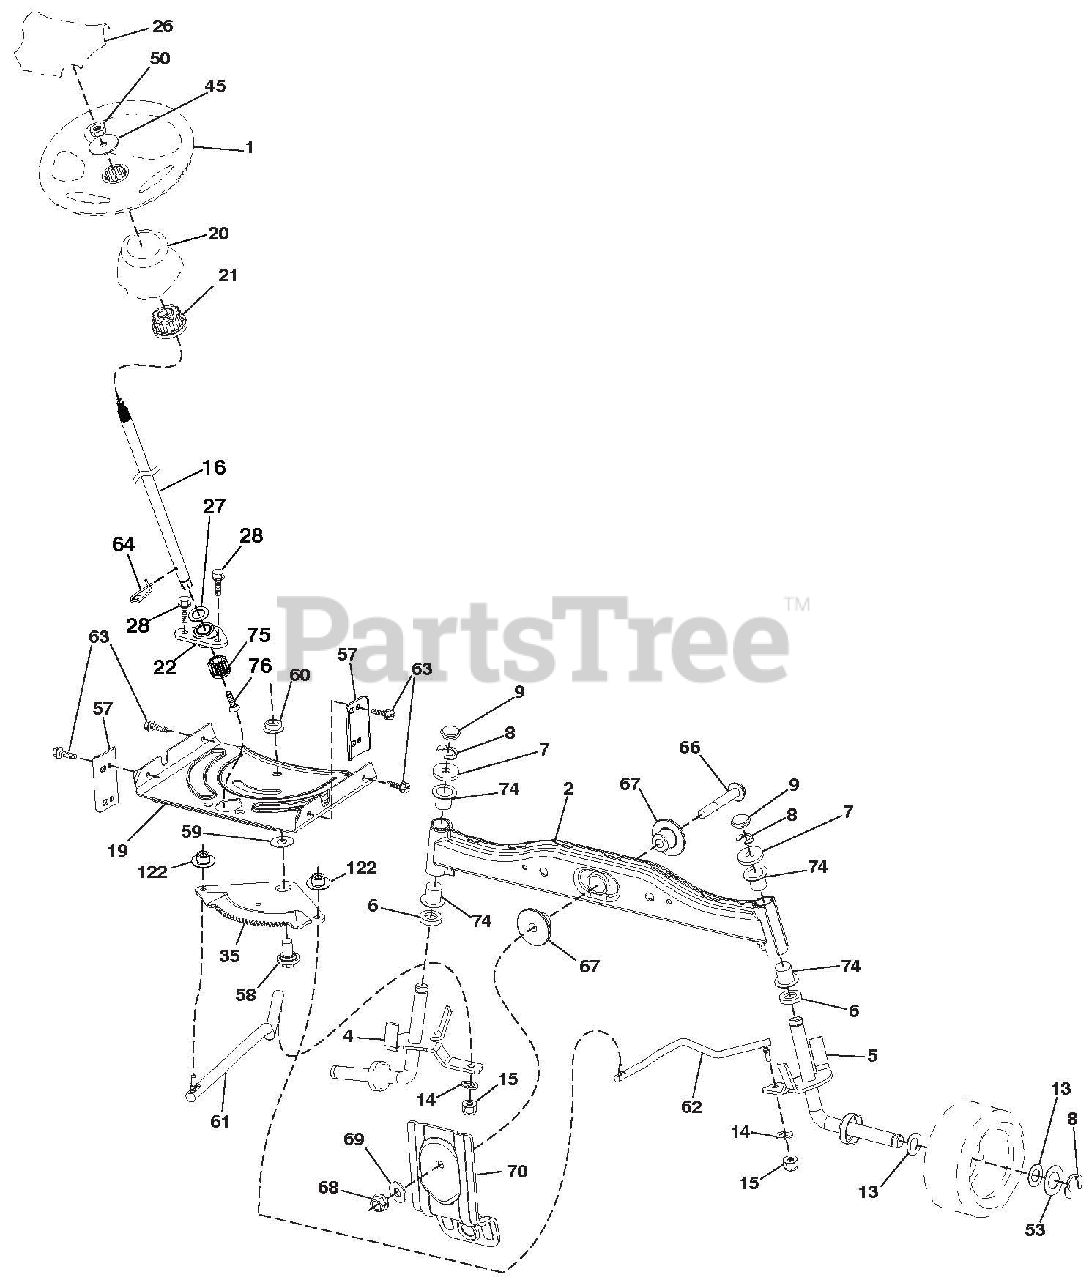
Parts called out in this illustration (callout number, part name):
1	WHEEL STEERING
2	AXLE ASM.WELDED
4	SPINDLE.WELDED.LH.15"TEX
5	SPINDLE.WELDED.RH.15"TEX
6	WAHSER THRUST .75 X 1.230
7	WASHER.25/32 X 1-5/8 X 16GA.
8	RING.KLIP.#T5304-75
9	CAP.SPINDLE.FR.TOP.BLK.
13	WASHER.25/32 X 1 1/4 X 16 GA.
14	Washer, Lock 3/8
15	NUT.CROWNLOCK.3/8-24
16	SHAFT STEER
19	PLATE.STEER.DDL.NLT/NGT
20	BOOT.STEERING
21	ADAPTER.STEER
22	STEER.SUPT. LOWER
26	CAP WHEEL STEERING HRS/SRS BLK
27	WASHER 21/32 X 1 X 1 GA.
28	SCREW.HEXWSH THDR3/8-16X3/4.BL
35	GEAR SECTOR.PLATE.DDL.NLT/NGT
50	Nut, Hex, Flangelock 3/8-16
53	WASHER.HARDEN..793 X 1.637X060
57	BRACKET.UPSTOP.TEX
58	BOLT.SHOULDER.SECTOR.PIVOT.CFM
59	WASHER.THRUST.SECTOR.STEER.NLT
60	NUT.FLANGE LOCK.5/8-11
61	DRAGLINK.LH.BALLSTUD.DDL.
62	DRAGLINK.RH.BALLSTUD.DDL
63	SCREW.5/16-18X3/4.SMGML.TAP/BL
64	RETAINER.CLIP.SPRING.STEERING
66	BOLT.HEX.FGHD.7/16-14 X 3.SERR
67	BUSHING.PM.FRONT AXLE
68	NUT.LOCK.FLANGE.7/16-14.GR5
69	WASHER.1.5 X .505 X .118
70	BRACKET
74	BEARING COL STRNG BLK
122	CAP GEAR SECTOR
